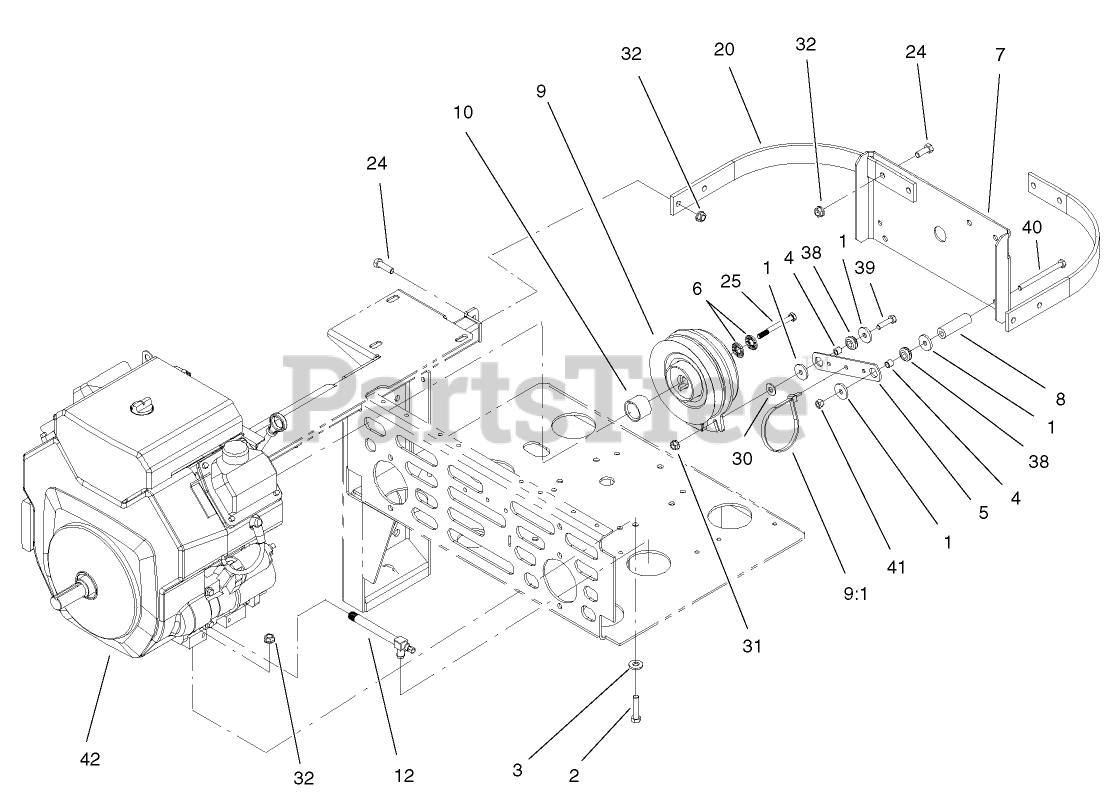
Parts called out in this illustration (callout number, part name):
1	WASHER
2	SCREW-HH
3	WASHER-BELLEVILLE
4	SPACER
5	STRAP-CLUTCH, BRAKE
6	WASHER-SPRING
7	GUARD-CLUTCH
8	SPACER-ANCHOR, CLUTCH
9	CLUTCH ASM
9:1	TIE-PLASTIC
10	SPACER-CLUTCH
12	VALVE-OIL DRAIN, LONG
20	BRACKET-GUARD, TOP
24	SCREW-HH
25	SCREW-HH
30	WASHER-FLAT
31	NUT-HF
32	NUT-HHF, WHIZ
38	GROMMET
39	SCREW-HH
40	SCREW-HH
41	NUT-LOCK, NI
